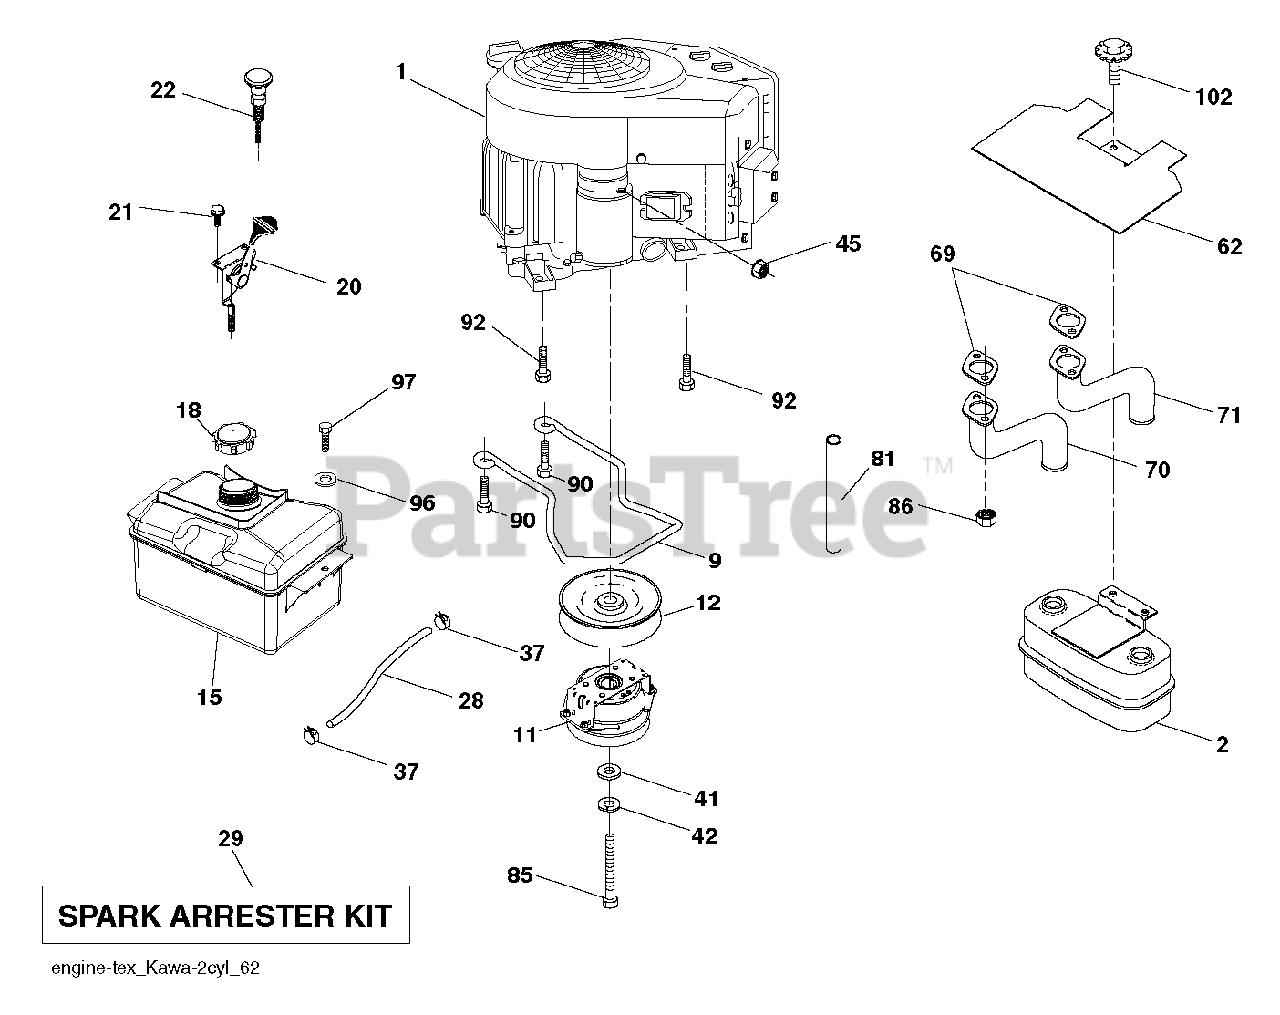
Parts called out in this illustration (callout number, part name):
2	MUFFLER.ASM.TWN.EXTNDED.DFLCTR
9	KEEPER.BELT.ENG.4.25"2.BLT.431
11	CLUTCH.OGURA.5.0PD.GT1.5A-EH07
12	PULLEY.ENGINE.TUFFTORQ
15	TANK.ASSEMBL.2.5GAL.NON-EPA
18	CAP ASM.FUEL.2.25"FR.
20	CONTROL.THROTTLE.COBRA.BLACK
21	SCREW.#10 X 0.750.BOS
22	CONTROL.CHOKE.ERGO.PUSH-IN.BLA
28	HOSE.14.FUEL.LINE.60.
29	KIT.SPARK ARRESTOR 794945 B&S
37	HOSE CLAMP
42	WASHER 7/16 LOCK
45	NUT
62	SHIELD.HEAT.MUFFLER
69	GASKET.MUFFLER
70	EXHAUST.TUBE.LH.BS/TWIN
71	EXHAUST.TUBE.RH.B&S.TWIN.INTEK
81	TUBE, DRAIN OIL ASM.
85	BOLT.HEX.7/16-20X3.75.GR5.RED
86	NUT.HEX.FLANGE.TOPLOCK
90	SCREW 3/8-16X1
92	SCREW 3/8-16X1
97	SCREW HEXWSHR 1/4-20X3/4
102	SCREW
